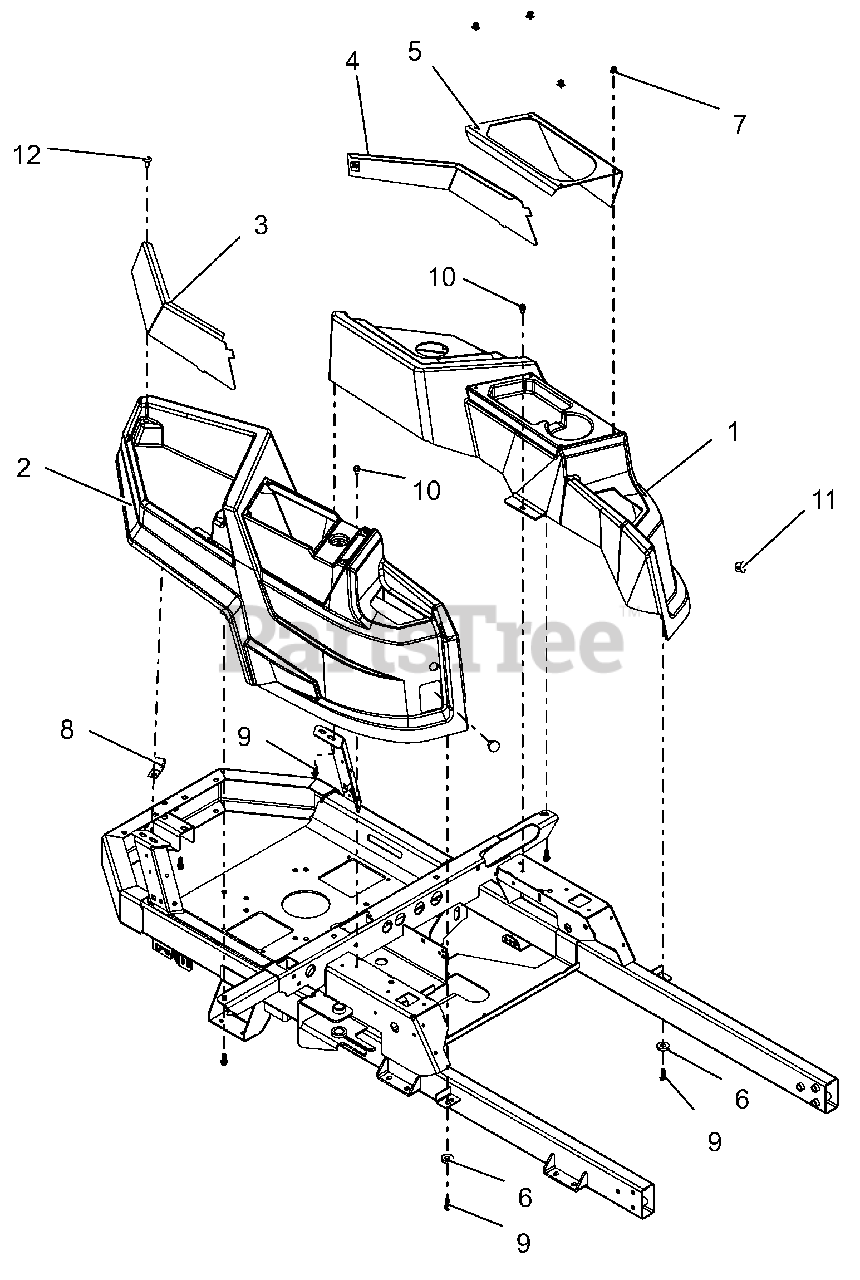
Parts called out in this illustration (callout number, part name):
1	FENDER, LH -ZOOM
2	FENDER, RH -ZOOM
3	WLDMT, FENDER BLOCKOFF-RH XL
4	WLDMT, FENDER BLOCKOFF XL -LH
5	PANEL, CUPHOLDER/STORAGE (LH)
6	WSHR, FLT .406X1.00X.188 ZCC
7	RIVET, PLASTIC .195 DIA.
9	SCR-.312X.75 #14H H/W/H H/L CZ
10	SCR-TAP .25-20X.50 HWH ZCC
11	PLUG, HOLE .75 (BLACK)
12	XMAS TREE FASTNER-BLACK
